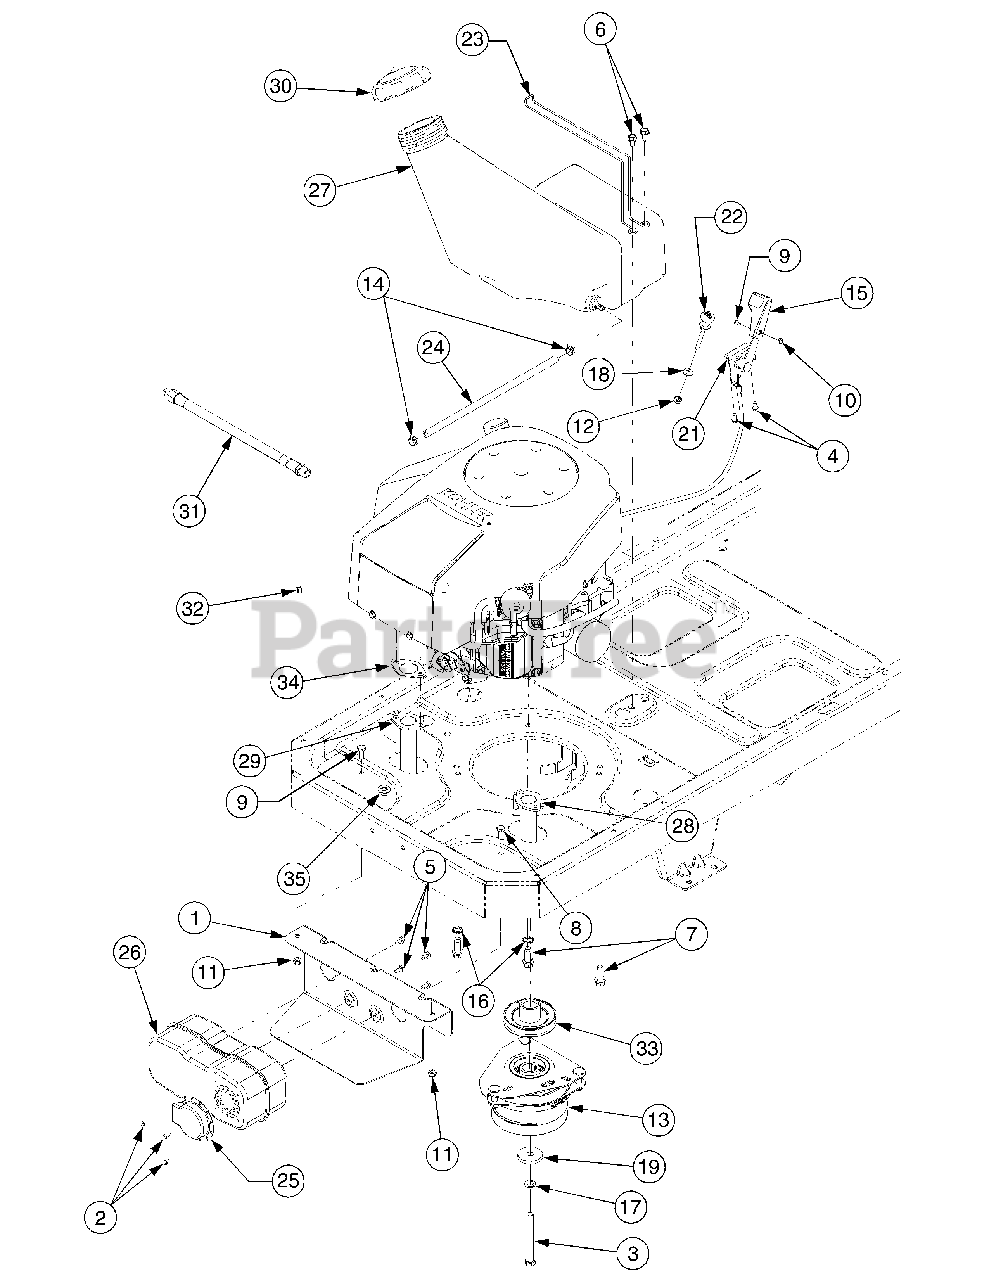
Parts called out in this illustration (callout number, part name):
1	Bracket, Muffler Mounting
2	Screw, Hex Wash. Hd. Tapp #8-18 x .5
3	Screw, Hex Cap, 7/16-20 x 4.0 GR5
4	Screw, Hex Wash. Hd. Tapp #12-16 x .5
5	Screw, Hex Wash. Hd. Tapp 1/4-20 x .5
6	Screw, Hex Wash. Hd. Tapp 5/16-12 x .75
7	Screw, Hex Wash. Hd. Tapp Sems 3/8-16 x 1.0
8	Screw, Hex Cap, 5/16-18 x .75 GR5
9	Screw, Truss Hd. Mach. #8-32 x .375
10	Nut, Hex, #8-32
11	Nut, Hex Insert Lock, 5/16-18 GR5 ..
12	Nut, Hex Jam, 3/8-16 GR2
13	Clutch Assembly, Electric PTO
14	Clamp, Hose
15	Knob, Throttle Control
16	Washer, External Tooth Lock, 3/8
17	Washer, Lock, 7/16
18	Washer, Flat, .406 x .875 x .059
19	Washer, Flat, .438 x 1.75 x .25
21	Cable, Throttle, 34.25 Lg
22	Cable, Choke, 61Lg
23	Wire, Tank Mounting
24	Hose, Fuel Line 10 Inches
25	Deflector, Muffler
26	Muffler
27	Tank, Fuel, 3.0 Gal.
28	Pipe, Exhaust RH
29	Pipe, Exhaust LH
30	Cap, Fuel
31	Hose, Oil Drain Extension
32	Nut, Hex Sems, 1/4-20
33	Pulley, Drive
34	Gasket, Muffler
